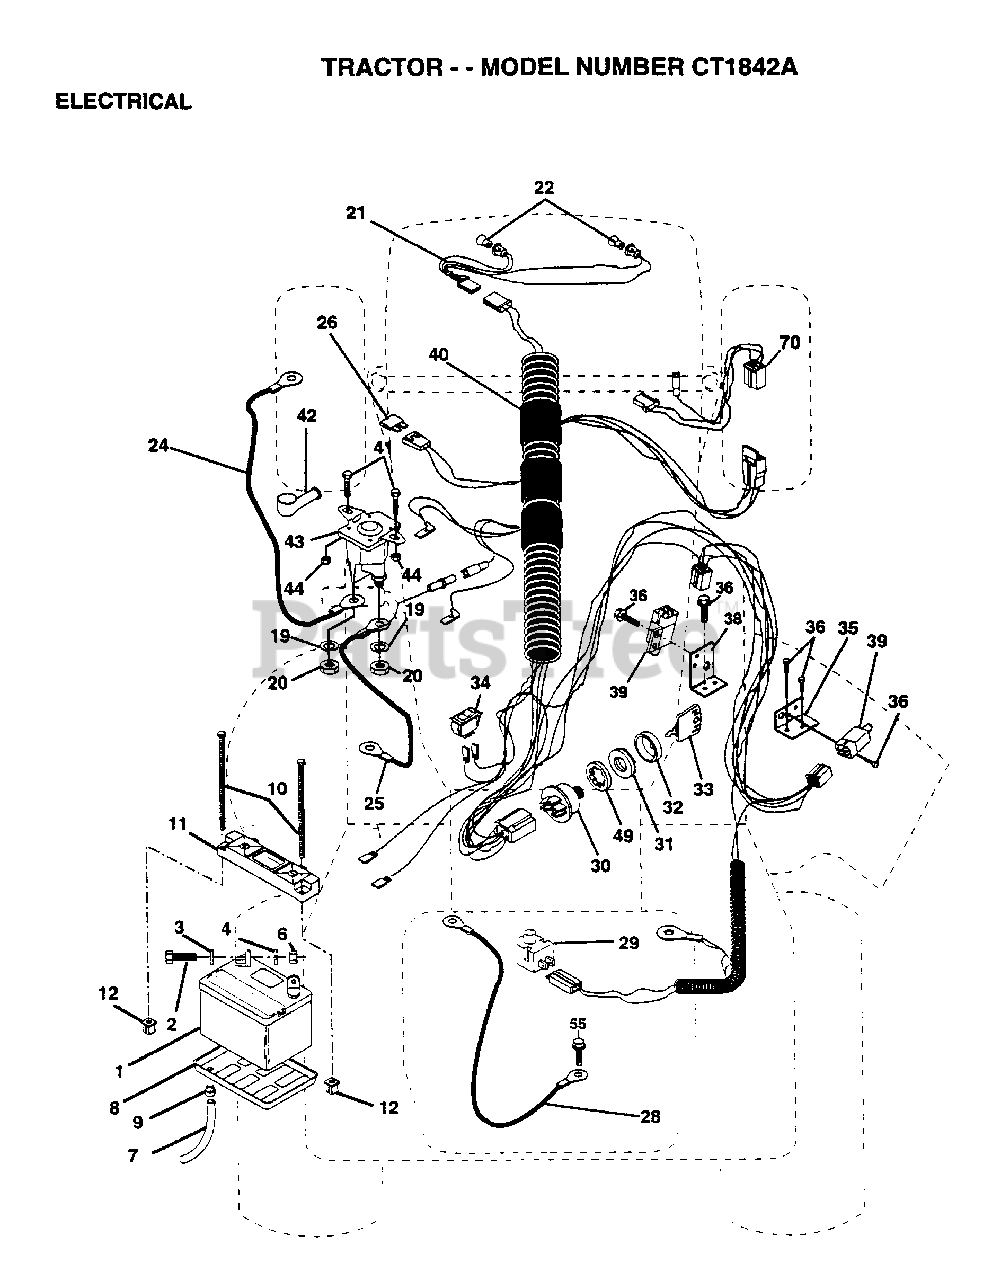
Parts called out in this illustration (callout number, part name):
2	BOLT LT
3	WASHER
4	LOCKWASHER
7	"DRAIN TU T, BATT"
8	"TRAY T, BATTERY"
9	HOSE CLAMP T
20	NUT
21	"HARNESS,LIGHT SOC"
22	HEADLAMP BULB
24	CABLE-BATTERY T
25	CABLE.6GA.22W/16W
26	FUSE HYT
28	CABLE.GRND.6GA.21
29	SWITCH SEAT
32	COVER KEY SWITCH
33	KEY MLD GEN DELTA
34	SWITCH LT
35	BRACKET LT
36	SCREW
38	BRACKET SWITCH IN
39	SWITCH INTERLOCKT
40	HARNESS.IGN.DASH.
41	BOLT.HX.1/4-20
44	NUT
49	LOCKWASHER
55	SCREW LT
70	HARNESS ENG DUAL
